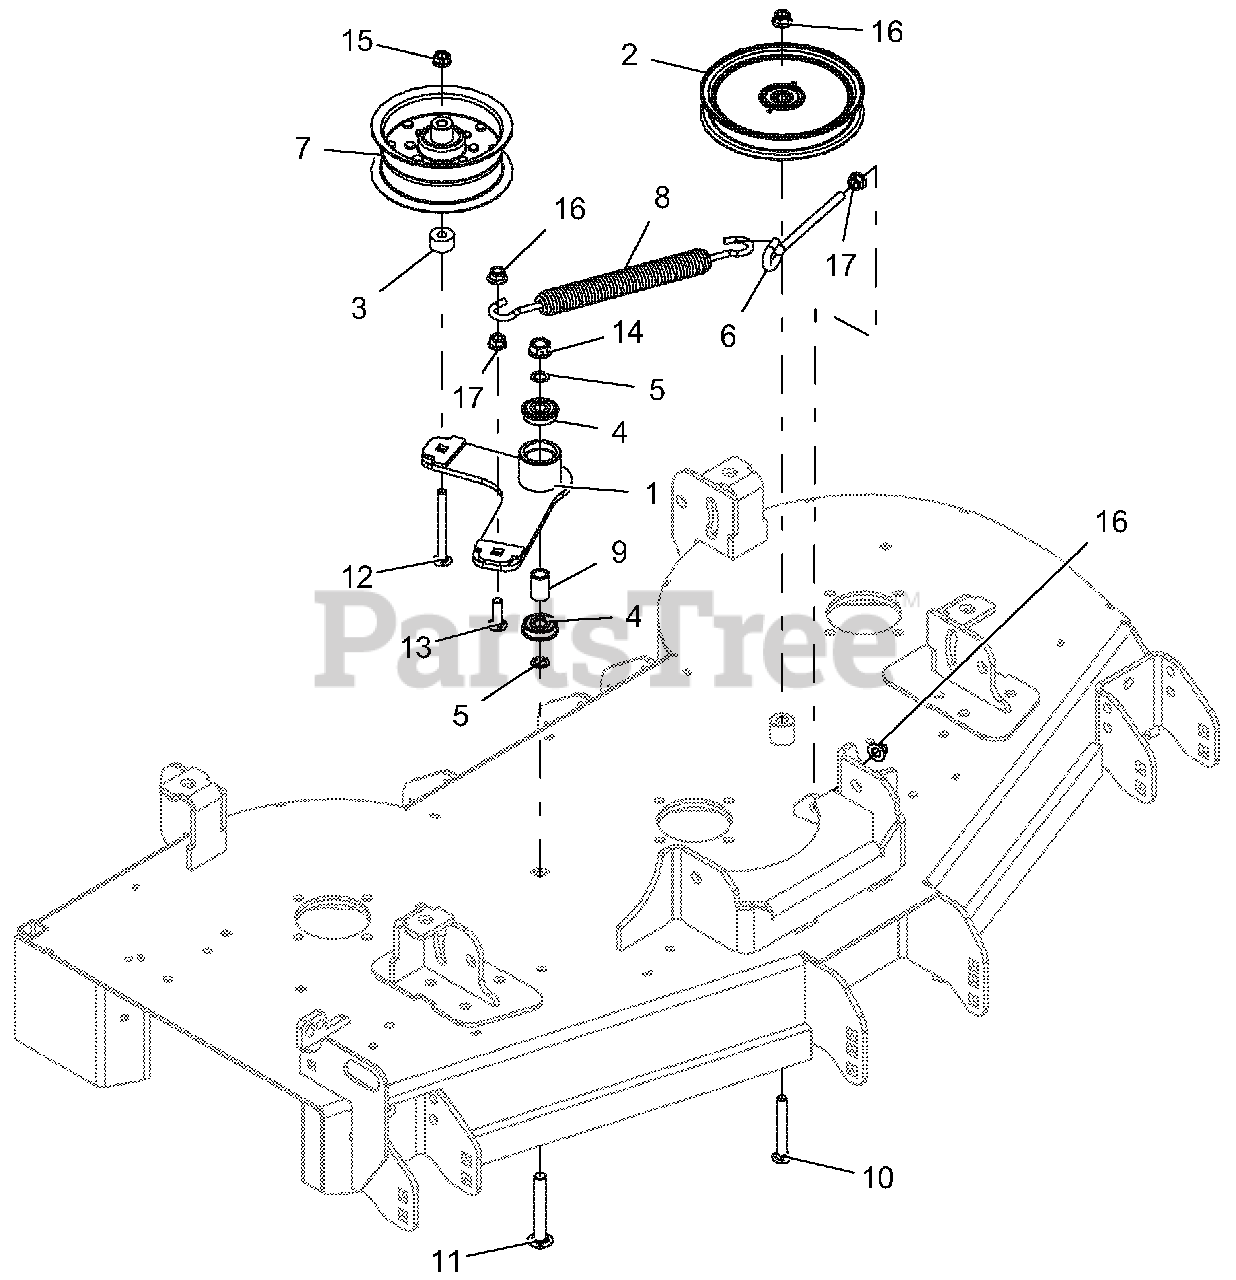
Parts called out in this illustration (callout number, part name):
1	WLDMT, IDLER ARM
2	IDLER, FLAT - 6.00" X .75"
3	SPACER .390X1.000X.562
4	BRG, BALL .501 X 1.38 X .438 SEALED
5	WASHER-FLAT-STL, .500 X .750 X .020
6	BOLT, EYE .38-16X6.00 .62 DIA
7	PULLEY, FLAT 5.00X2.36X.375
8	SPRG, EXTENSION
9	SPACER, .510 X .750 X 1.148
10	BLT-RDHDSQNK .38-16X3.00 G5 YWZC
11	BLT-RDHDSQSHNK .50-13X3.25 YWZC
12	BLT-RHDSSQNK .38-16X3.50 G5YZ
13	BLT-RHDSSQNK .38-16X1.25 G5YZ
14	NUT-LK-CTR-FLG .50-13 YWZC
15	NUT, LK-CTR-FLG .38-16 YWZC
16	NUT-LK-NYL-FLG .38-16 YWZC
17	@NUT-SPNLK-FLG .375-16 YWZC
